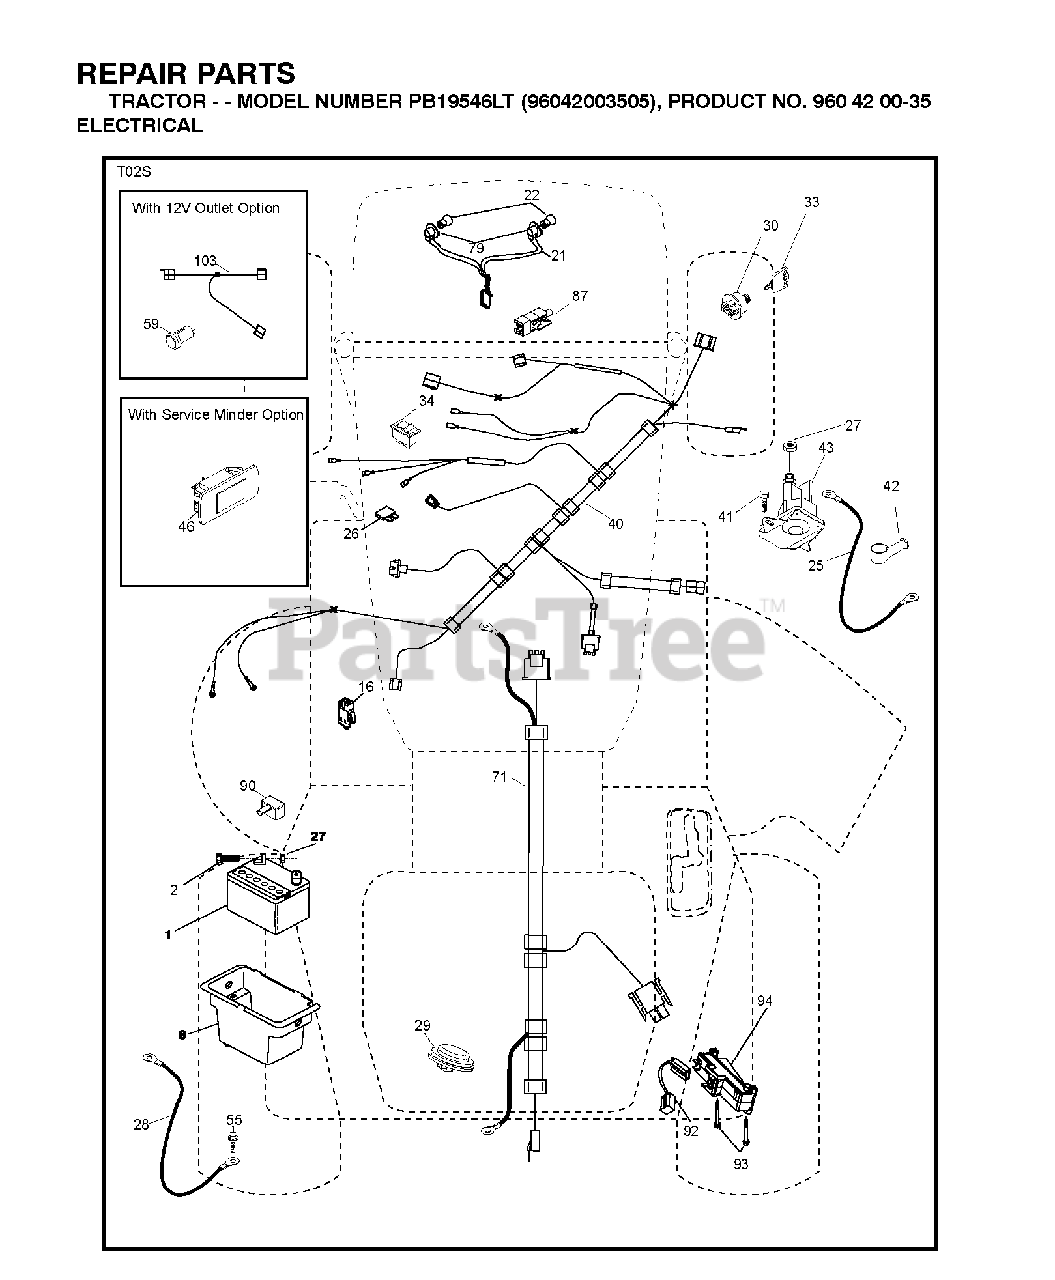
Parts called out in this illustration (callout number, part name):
1	REPL BY 532 12 38-99
2	BOLT.HEX.1/4.X.3/4.DICHROMATE
8	BOX.BATTERY.MNT.REAR.L
16	SWITCH INTERLOOK PUSH-IN
21	HARNESS ASSY LIGHT
22	LIGHTBULB
25	CABLE.STARTER.6GA.BL/RED.14.
26	FUSE 20AMP
27	NUT
28	CABLE.BLACK.18"REAR.BA
29	SWITCH.SEAT.DELTA.OPC.
30	SWITCH.IGN.DELTA.W.LGH.ROS
33	KEY.CHAIN.BLISTER.PACK.GEN.INT
34	SWITCH LT
40	HARNESS IGN. DASH
41	SCREW
42	TERMINAL COVER
43	SOLENOID.W/BRASS.PLUNGER
55	SCREW 5/16"
71	HARNESS.IGN.CHASS.TEX.REAR.BAT
79	BULB HOLDER ASM.
87	SWITCH.INTRLCK.CLUTCH.
90	COVER.TERMINAL.BATTERY
92	HARNESS.PIGTAIL.CONSLE
93	SCREW.PLASTITE
94	MODULE.REVERSE.ROS
